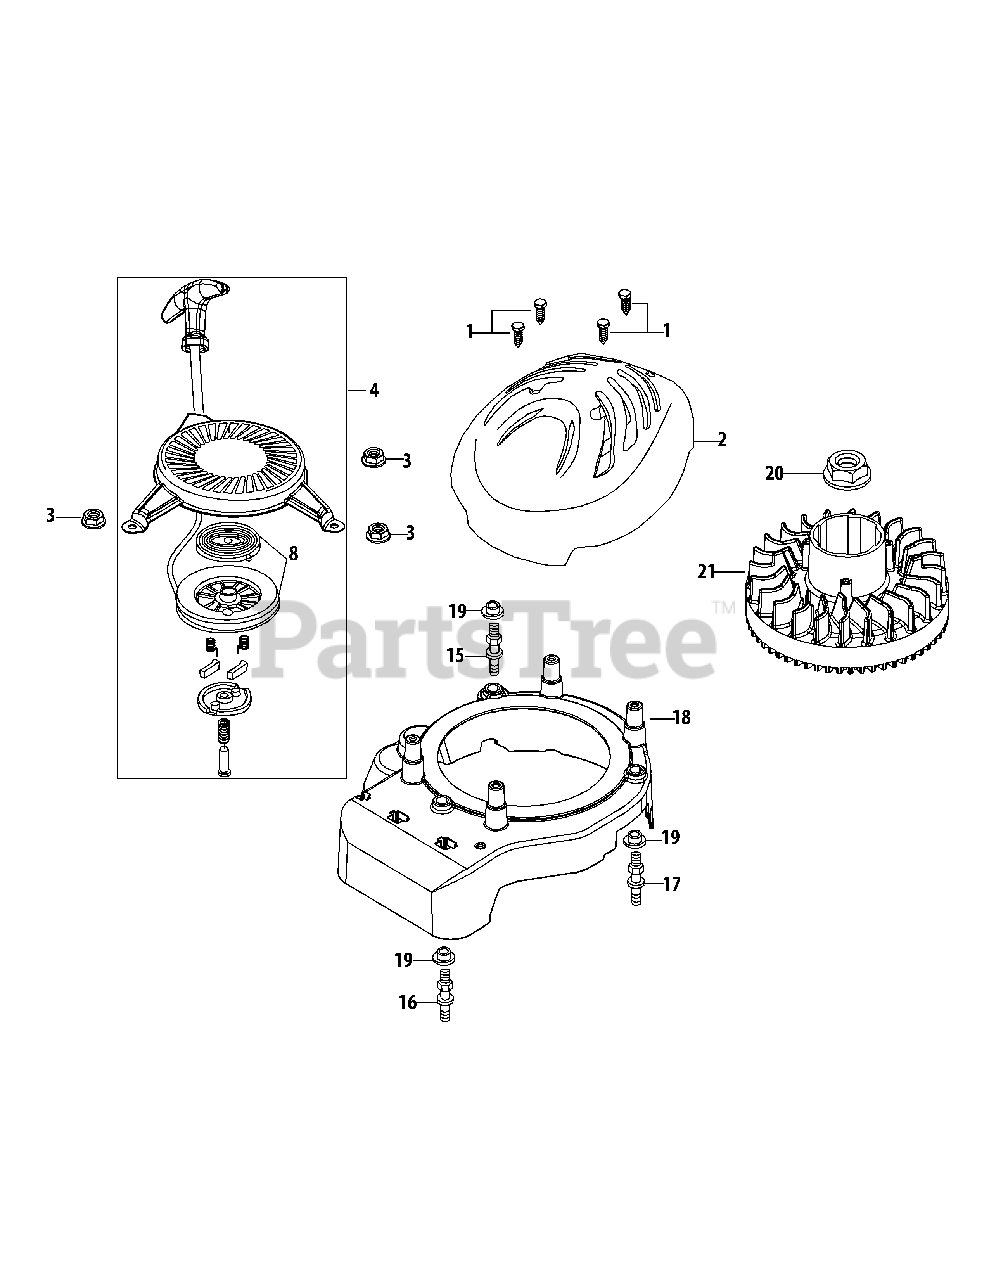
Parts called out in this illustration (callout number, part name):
1	Self-Tapping Bolt, Hilo #12-16 X 1.00"
2	Outer Shroud (Model Specific)
3	Nut M6X10mm
4	Recoil Starter Assembly
8	Recoil Spring And Pulley Ass'Y
15	Stud Left/Black/Wh Zinc
16	Stud Front/Unmarked/Wh Zinc
17	Stud Right/White/Wh Zinc
18	Inner Shroud
18	Inner Shroud (Incl.19)
19	Engine Shroud Spacer
20	Flywheel Nut M14
